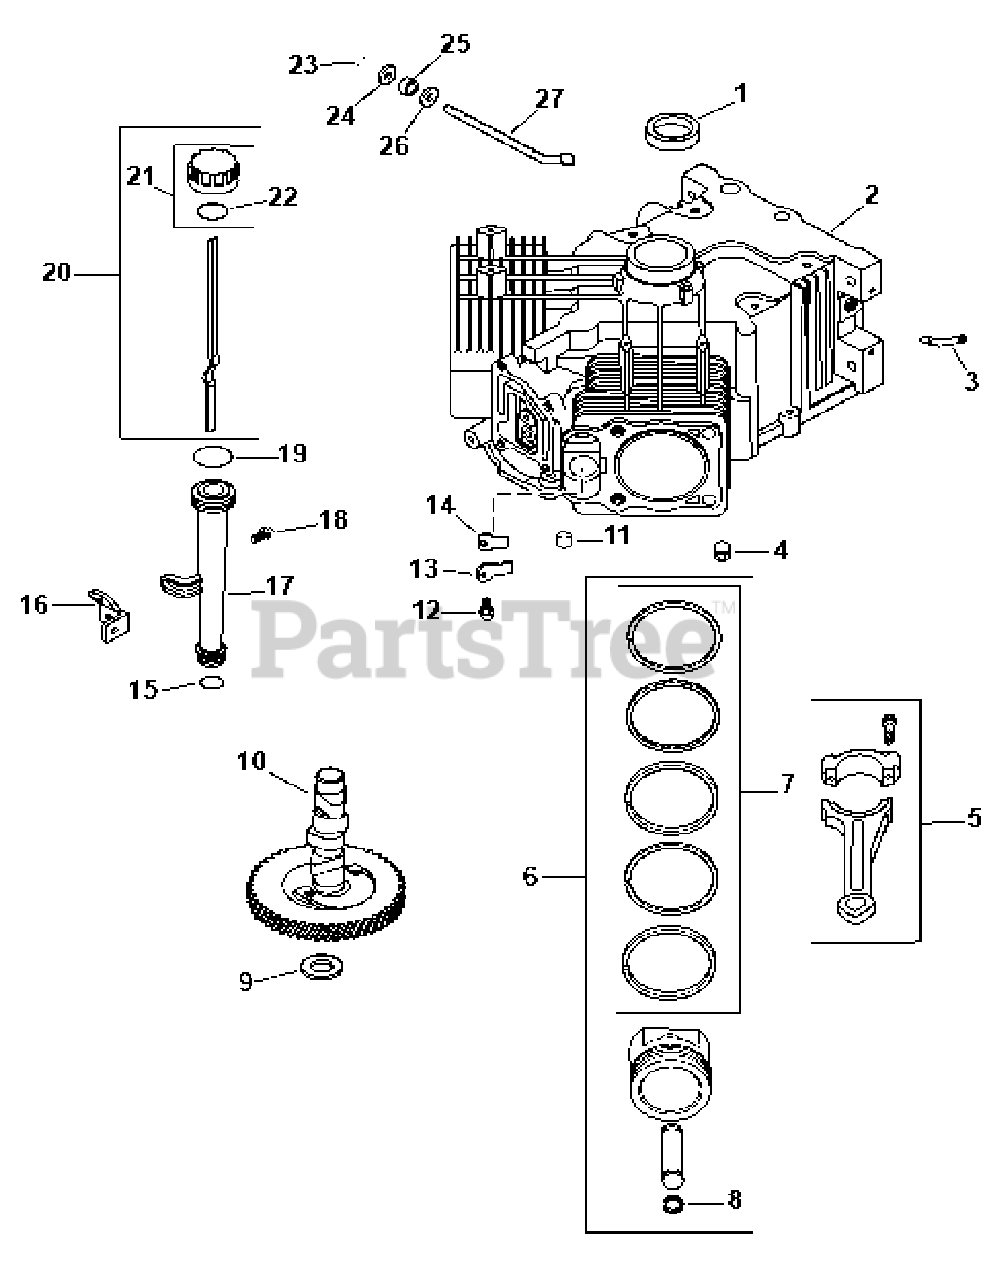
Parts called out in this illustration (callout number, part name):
1	Oil Seal
4	Split Dowel Pin
5	Connecting Rod (Std.)
5	Connecting Rod (.25)
6	Piston w/Ring Set Kit (Std.)
6	Piston w/Ring Set Kit (.08.)
6	Piston w/Ring Set Kit (.25.)
6	Piston w/Ring Set Kit (.50.)
7	Ring Set (Std. & .08)
7	Ring Set (.25)
7	Ring Set (.50)
8	Piston Pin Retainer
9	Shim (White)
9	Shim (Blue)
9	Shim (Red)
9	Shim (Yellow)
9	Shim (Green)
9	Shim (Gray)
9	Shim (Black)
10	Camshaft Kit
11	Cup Plug
13	Reed Retainer
14	Breather Reed
16	Oil Fill Tube Bracket
17	Oil Fill Tube
18	Screw
19	O-Ring Upper Fill Tube
21	Oil Fill Cap Kit
23	Ring Retainer
24	Plain 9mm washer
25	Oil Governor Shaft Seal
27	Governor Cross Shaft
